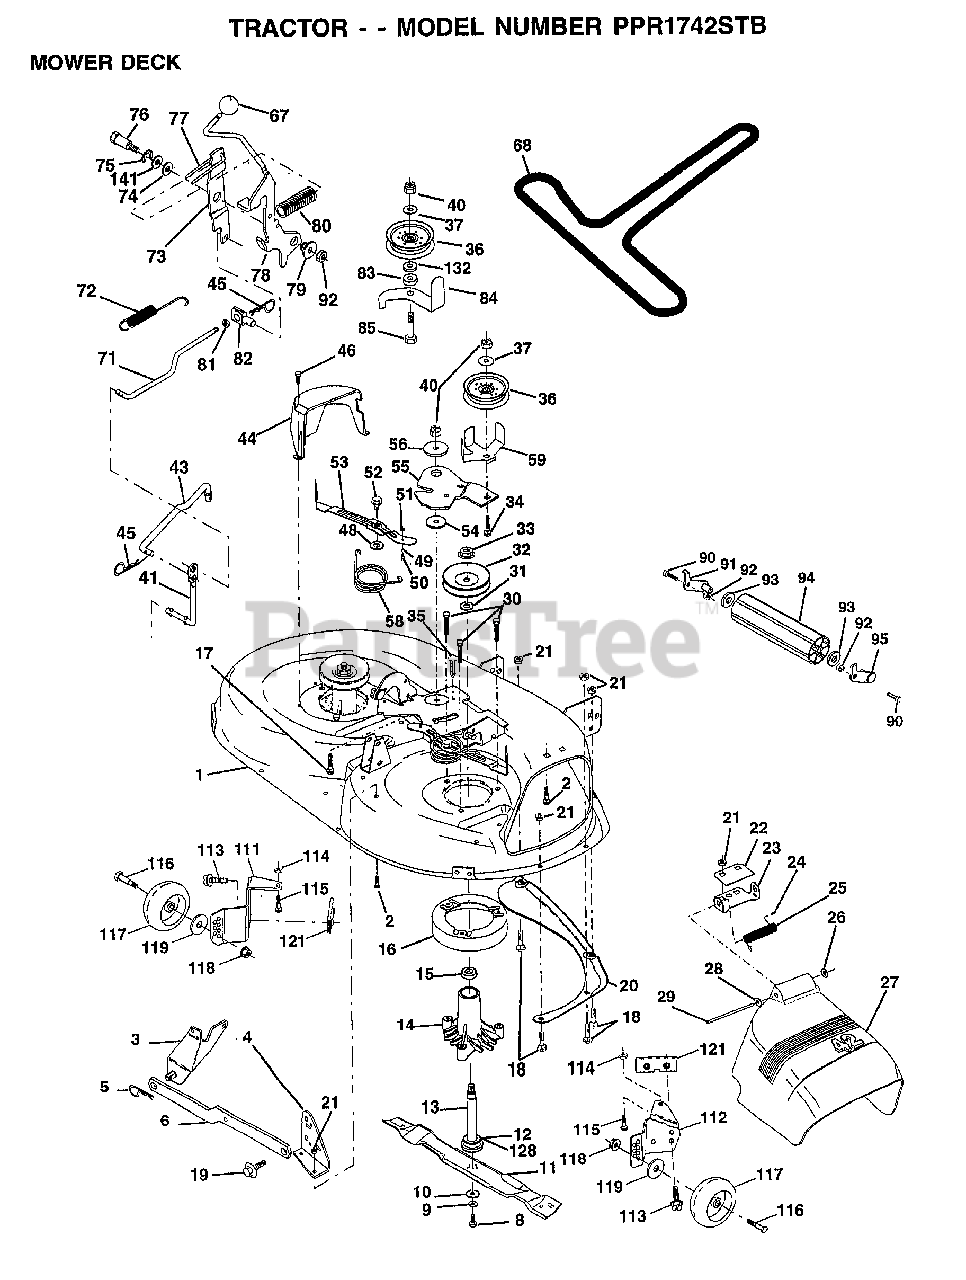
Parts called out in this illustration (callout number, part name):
1	"HOUSING ASSY.42"""
2	BOLT
3	BRKT ASM SWAY BAR
4	BRKT DECK SW BAR
8	BLADE BOLT
10	WASHER.HARD.BLADE
11	"BLADE.42"" HIPERF"
12	BEARING.BALL
14	HSG ASM MANDREL
15	BEARING
16	STRIPPER RND MWR
17	BOLT RDHD 3/8-16
18	BOLT
19	BOLT SHD 5/16-18
20	BAFFLE VORTEX 42
22	STIFFENER BRKT
23	DEFLECTOR BRKT
24	CAP-SLEEVE LT
25	SPRING TORSION
26	NUT PUSH M
27	DEFLECTOR.SHIELD
29	WASHER
29	HINGE ROD
30	"SCREW-THD ROLL,WA"
31	WASHER
32	PULLEY.MANDREL.42
34	BOLT
35	XMAS TREE FASTNER
36	FLAT IDLER PULLEY
37	WASHER
41	PIVOT ROD
43	ROD CLUTCH W/NIBS
44	GUARD MAND LH BLK
45	RETAINER M
46	SCREW.1/4-20X5/8
48	HARD SMALL WASHER
49	ROLLER ASM-CAM
50	SHOULDER BOLT
51	LOCKNUT
52	BOLT.SHLD.5/16-18
53	BRAKE PAD ARM ASM
54	HARDENED WASHER
55	ARM-IDLER
56	SPACER.RETAINER.MOWER
58	SPRING TORSN BRAK
59	GUARD IDLER TUV
67	KNOB.RD.7/16-14
68	BELT.V.T-PATH
71	ROD CLUTCH 38/42
72	RETURN SPRING
73	CLUTCH ARM SECOND
74	WASHER
75	RING
76	SHOULDER BOLT
77	SPRING KEEPER
78	LEVER.ASM.CLUTCH
79	BUSHING
80	SPRING.CLUTCH.MWR
81	NUT
82	TRUNION ADJ
83	WASHER
84	"KEEPER-BELT,FIXED"
85	BOLT
90	BOLT
92	NUT
93	WASHER
111	BRACKET.GWHL.LH.
112	BRACKET.GWHL.RH.
113	SCREW
116	BOLT M
117	WHEEL.GUAGE
118	LOCKNUT
119	WASHER
121	BRACKET.EXTRD.GWL
128	WASHER.FELT.
132	WASHER GT
141	WASHER .T
